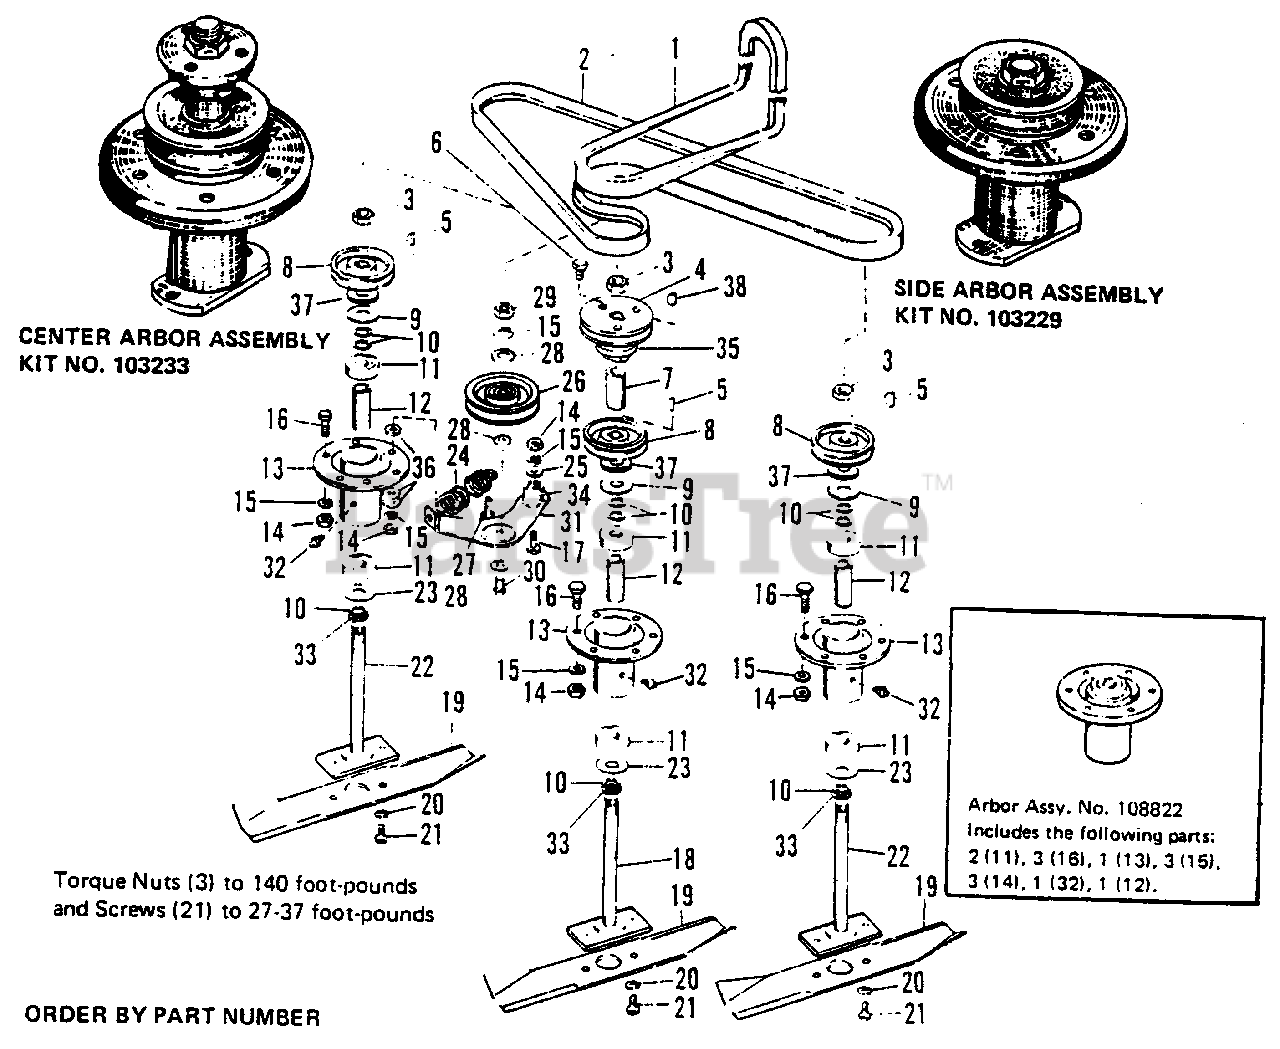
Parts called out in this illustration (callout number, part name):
2	Belt, "V" (Mower Spindle Drive)
3	Hex Nut, Jam Lock, 3/4"-16
5	Woodruff Key, (No. 61)
6	Screw, Washer-head, Taptite 3/8"-16 x 1-3/4"
9	Backing Ring
13	Arbor Tube Assembly
14	Full Hex Nut, 3/8"-16
15	Lockwasher, 3/8"
16	Hex Capscrew, 3/8"-16 x 3/4"
17	Hex Capscrew, 3/8"-16 x 1-3/4"
18	Arbor Drive Assembly
19	Knife Blade
20	Lockwasher, 3/8"
21	Hex Capscrew, 3/8"-16 x 5/8"
22	Arbor Assembly
25	Plain Washer, 5/16"
26	Idler Pulley
28	Plain Washer, 5/16"
29	Full Lock Hex Nut, 3/8"-16
31	Idler Lever Assembly
32	Grease Fitting
34	Race Inner Bearing
35	Hub, Pulley
36	Washer, 5/16"
